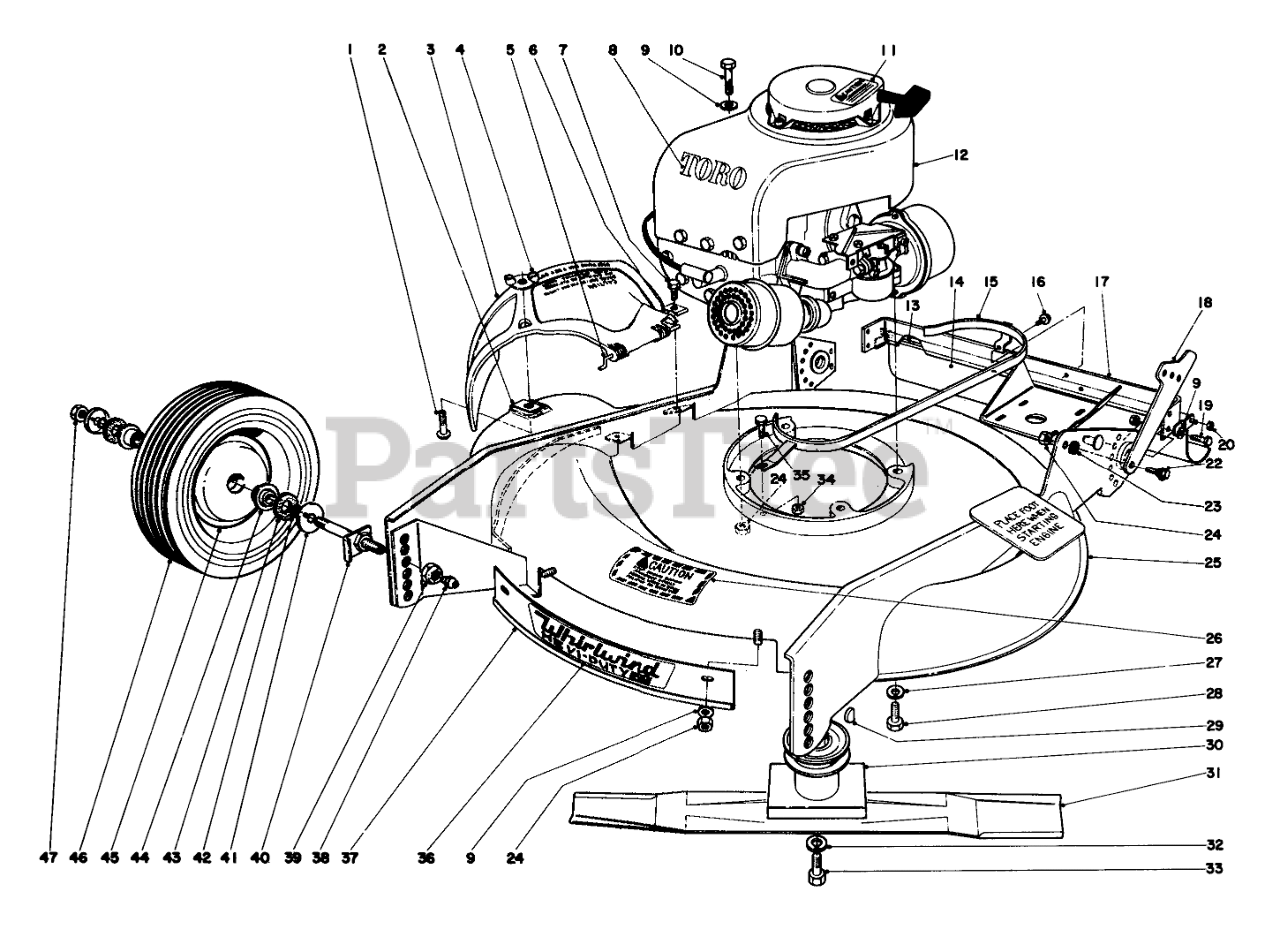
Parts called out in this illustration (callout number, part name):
2	NUT-SPEED
3	Deflector
4	NUT-WING SPECL
6	Clamp
7	1/4-20X1/2 THDG SEMS
8	DECAL
9	WASHER-PLAIN
10	SCREW-HH
11	Decal Caution
13	SHIELD ROD
14	Rear Safety Shield
15	Belt Guide
16	Screw
17	Support-Gear Case
18	Latch
19	SCREW-HH
20	NUT-LOCK, NI
21	NUT-LOCK NI
22	SCREW-SHOULDER
23	SPACER
24	Nut
27	WASHER-LOCK
28	SCREW-HH
29	KEY-WOODRUFF
30	Blade Retainer
31	Blade
32	WASHER-LOCK
33	SPECIAL SCREW
34	NUT-LOCK
35	SCREW-HH
36	Decal
38	FITTING-GREASE
39	NUT-LOCK, NI
40	Spindle Ass-y. (Incl. Ref. #29)
41	SLINGER
42	O-RING
43	Washer
44	BEARING-BALL
45	Wheel (Incl. Ref. #53)
46	1.75-8 SEMIPNEU TIRE
47	Nut
